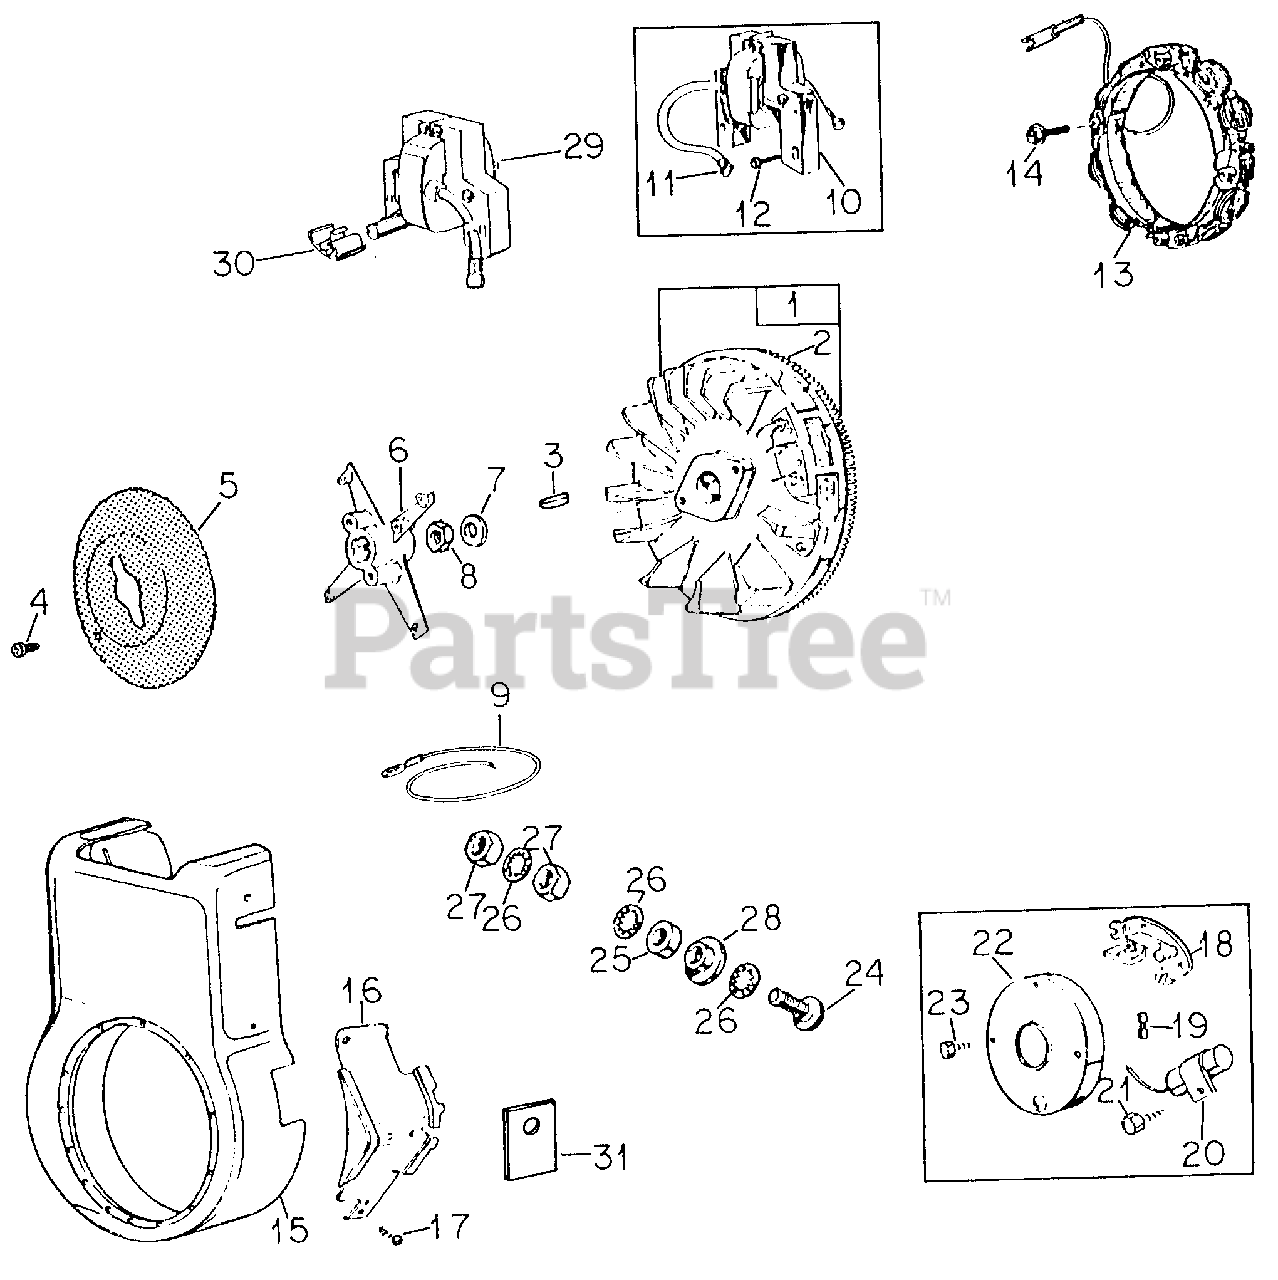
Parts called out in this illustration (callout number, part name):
1	Flywheel w/Ring Gear Assy, Magneto
2	Gear, Flywheel Ring
3	Key, Flywheel
4	Screw, Flywheel Screen
5	Screen, Flywheel
6	Fan, Booster
7	Washer, Spring
8	Nut, 5/8-NF Jam Type 5
9	Wire, Ground
10	Armature Assy, Magneto
11	Terminal, Magneto Cable
12	Screw, Armature Mounting
13	Stator, Alternator
14	Screw, Stator Mounting
15	Housing, Blower
16	Cover, Starter Shield
17	Screw, Starter Shield
18	Breaker Assy, Ignition Points
19	Plunger, Breaker Points
20	Condenser
21	Screw, Condenser Mounting
22	Cover, Points & Condenser
23	Screw, Cover Mounting
24	Screw, Terminal Mounting
25	Washer, Insulating
26	Washer, No. 8 Int Tooth Lock
27	Nut, No. 8-32 Hex Mach Screw Terminal
28	Collar, Insulating
29	Armature Assy
30	Shield, Capsule
31	Retainer, Wire
